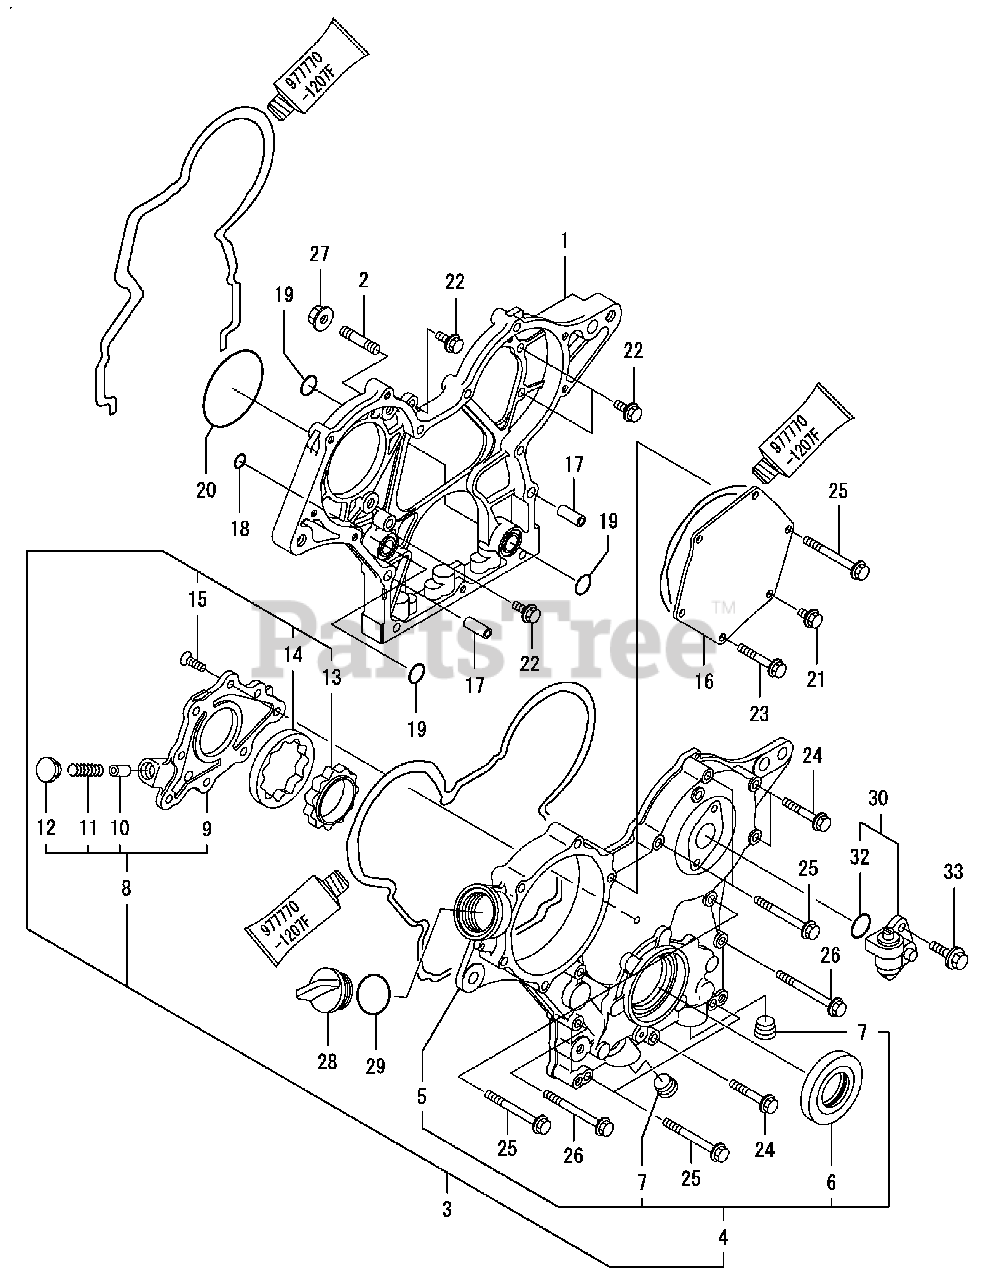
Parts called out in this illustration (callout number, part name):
3	COVER ASSY,GEAR CASE
4	COVER ASSY,GEAR CASE
5	COVER, GEAR CASE
7	PLUG PT3/8,SCREW
8	COVER ASSY, PUMP
9	COVER, LUB.OIL PUMP
16	COVER, PUMP TIMING
20	O-RING, F.I.PUMP
21	BOLT M 6X 12 PLATED
22	BOLT M 6X 16 PLATED
23	BOLT M 6X 40 PLATED
24	BOLT M 6X 40 PLATED
25	BOLT M 6X 60 PLATED
26	BOLT M 6X 65 PLATED
29	O-RING 1A P-32.0
30	GEAR UNIT,TACHOMETER
32	O-RING 1A S-24.0
33	BOLT M 6X 16 PLATED
